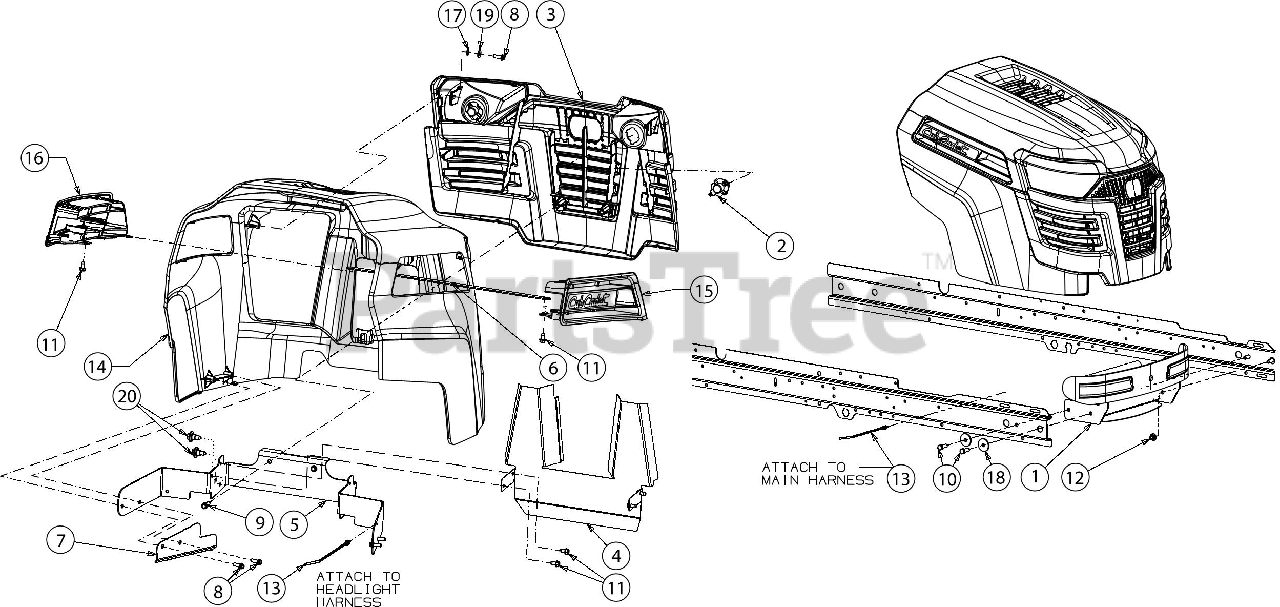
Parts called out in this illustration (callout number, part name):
1	FRONT BUMPER ASSEMBLY
2	MINIATUURE BULB 12V
3	GRILLE ASSEMBLY
4	DEFLECTOR SHIELD
5	HOOD PIVOT BRACKET
6	HOOD CROSS BRACE
7	HEAT EXHAUST SHIELD
8	SCREW 1/4 x .750
9	SCREW 5/16-14 x 1
10	SCREW 3/8-16 x 1 GR5
11	SCREW 1/4-20 X.500
13	PUSH MOUNT TIE
14	HOOD (CUB YELLOW)
15	HOOD SCOOP (RH)
16	HOOD SCOOP (LH)
17	LOCK WASHER 1/4
18	FLAT WASHER .390x1.500x.134
19	FLAT WASHER .271:.630:.065
20	SHOULDER SCREW .43X.29X5/16-18 TT
